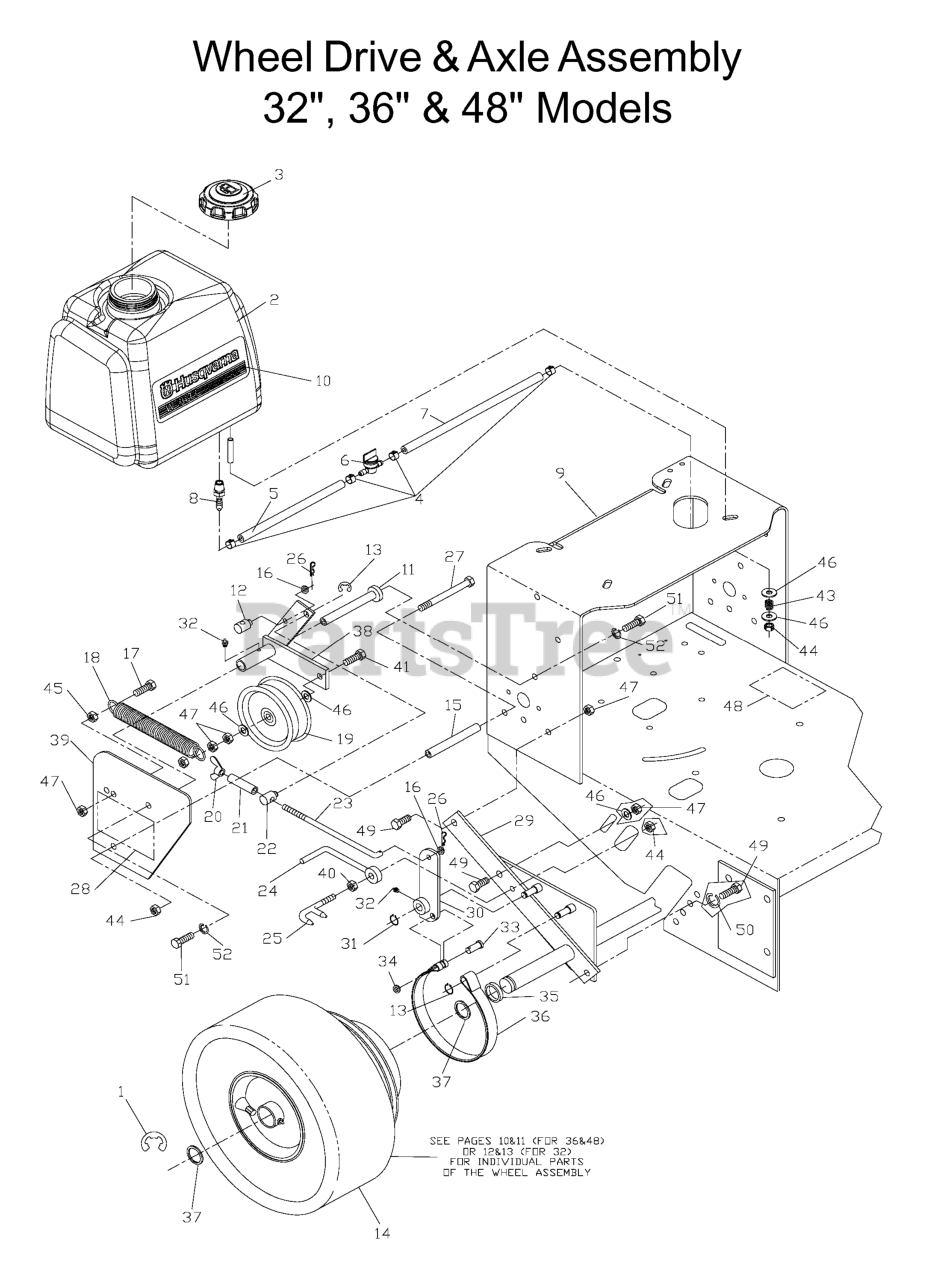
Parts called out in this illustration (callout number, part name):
1	E-RING 1"
3	FUEL CAP ANTI-SPLASH
4	HOSE CLAMP
5	GAS LINE 10"
6	FUEL VALVE
7	FUEL LINE 14"
8	HOSE BARB 90 DEGREE
9	REAR DECK W/DECALS
10	DECAL, W3213
11	SHOULDER PIVOT TUBE
12	SWIVEL (SHORT)
13	E RING 3/8"
14	WHEEL PARTS KIT
15	SPACER, LONG
16	WASHER 5/16 FLAT
17	HCS 3/8C X 1 1/4 GR5
19	PULLEY, IDLER
20	WINGNUT, 5/16C NYLOC
24	BELT GUIDE
25	SCRAPER (36 & 48)
26	HAIRPIN #2
27	HCS 5/16C X 5
28	DECAL, CRN H 3-1/8 SILVER
29	AXLE WELDMENT (36 & 48)
30	BRAKE ARM, RIGHT
31	E-RING 1/2 (2 2)
32	ZERK
33	CLEVIS PIN
34	NUT 3/8 PALNUT RTNG BLK PHOS
36	BRAKE BAND
37	MACHINE BUSHING
38	IDLER PLATE, RIGHT
40	NUT 5/16C WHIZ
41	TAPBOLT, 3/8C X 3
42	STUD, 5/16C
44	NUT 5/16C CENTERLOCK
45	NUT 3/8C WHIZ
46	WASHER 3/8 FLAT
47	NUT 3/8C CENTERBLOCK
48	DECAL, PROP. 65
49	HCS 3/8-16X1.GRD.5.ZD
50	SLW 3/8 STD
51	HCS 5/16C X 1
52	WASHER.LOCK.HVY.HLCL.SPR.5/16
539102135	BRAKE ARM, LEFT
539102152	AXLE WELDMENT (32)
539102169	IDLER PLATE, LEFT
539104829	DECAL, W3613
539104831	DECAL, W4815
